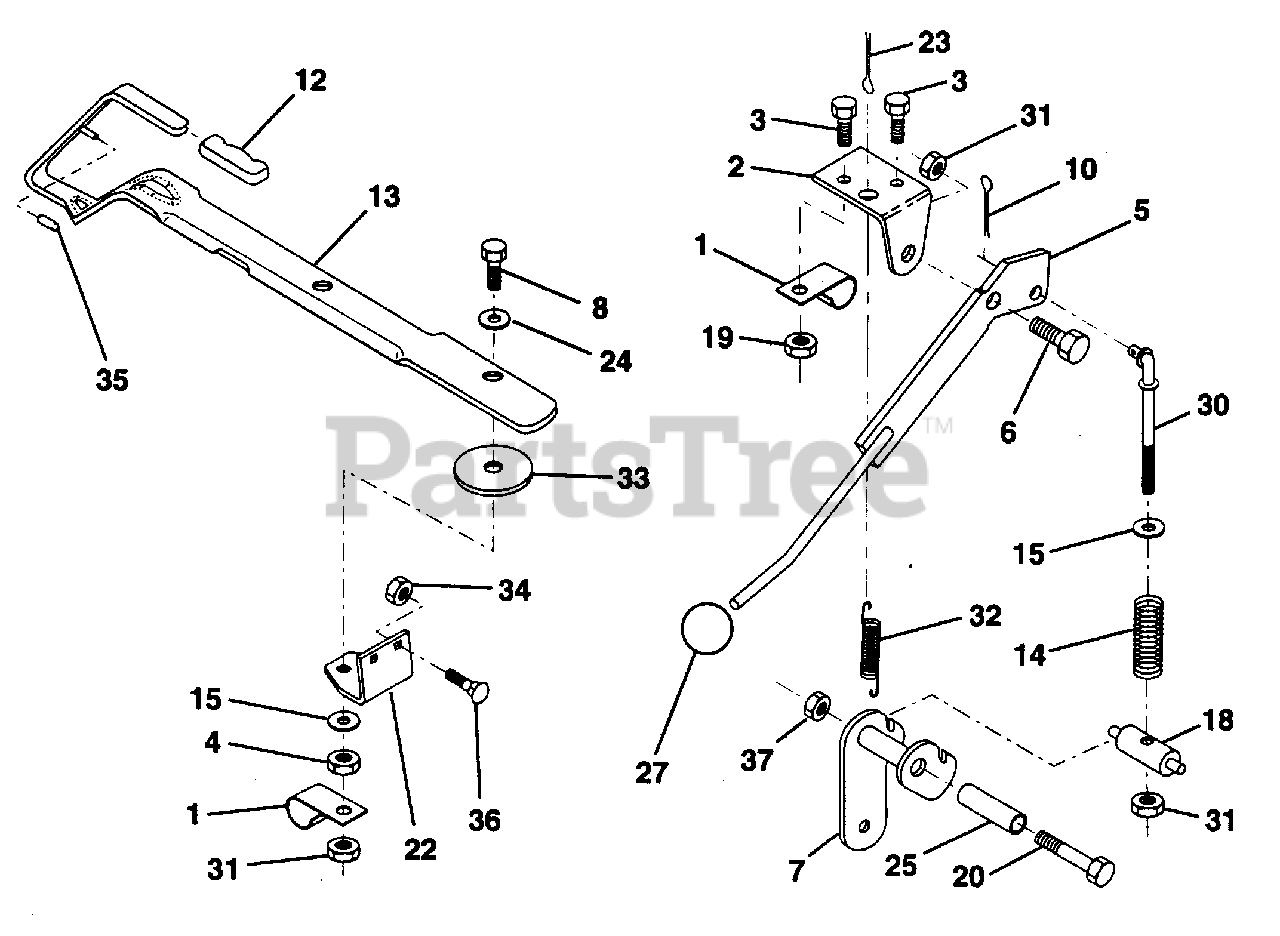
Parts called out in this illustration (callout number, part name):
1	Clip, Insulated (AYP part number)
2	Bracket, Mower Clutch (AYP part number)
3	Bolt, Hex Head, Fin. 1/4-20 UNC x 1/2 Grade 5 (AYP part number)
4	Nut, Centerlock (AYP part number)
5	Assembly, Clutch Lever (AYP part number)
6	Bolt, Shoulder (AYP part number)
7	Assembly, Mower Clutch Arm (AYP part number)
8	Bolt, Hex Head 3/8-16 UNC x 1-1/2 (AYP part number)
10	Pin, Cotter 1/8 x 3/4 (AYP part number)
12	Handle, Lift Lever (AYP part number)
13	Assembly, Lift Handle (AYP part number)
14	Spring, Compression (AYP part number)
15	Washer 13/32 x 1 x 11 Gauge (AYP part number)
18	Trunnion, Threaded 3/8-16 (AYP part number)
19	Nut, Crownlock 1/4-20 (AYP part number)
20	Bolt, Hex Head, Fin. 3/8-16 UNC x 2-3/4 (AYP part number)
22	Bracket, Lift Lever (AYP part number)
23	Pin, Cotter 3/32 x 3/4 (AYP part number)
24	Washer 25/64 x 1-1/4 x 12 Gauge (AYP part number)
25	Tube, Spacer (AYP part number)
27	Knob (AYP part number)
30	Rod, Tension, Clutch (AYP part number)
31	Nut Lock Hex w/wsh 3/8 - 16 (AYP part number)
32	Spring, Extension, Return (AYP part number)
33	Washer .390 x 1.437 x .074 (AYP part number)
34	Nut, Lock Hx w/Ins 5/16-18 (AYP part number)
35	Cap, Vinyl, Red (AYP part number)
36	Bolt, Carriage 5/16-18 x 3/4
37	Nut Crownlock 3/8-16
